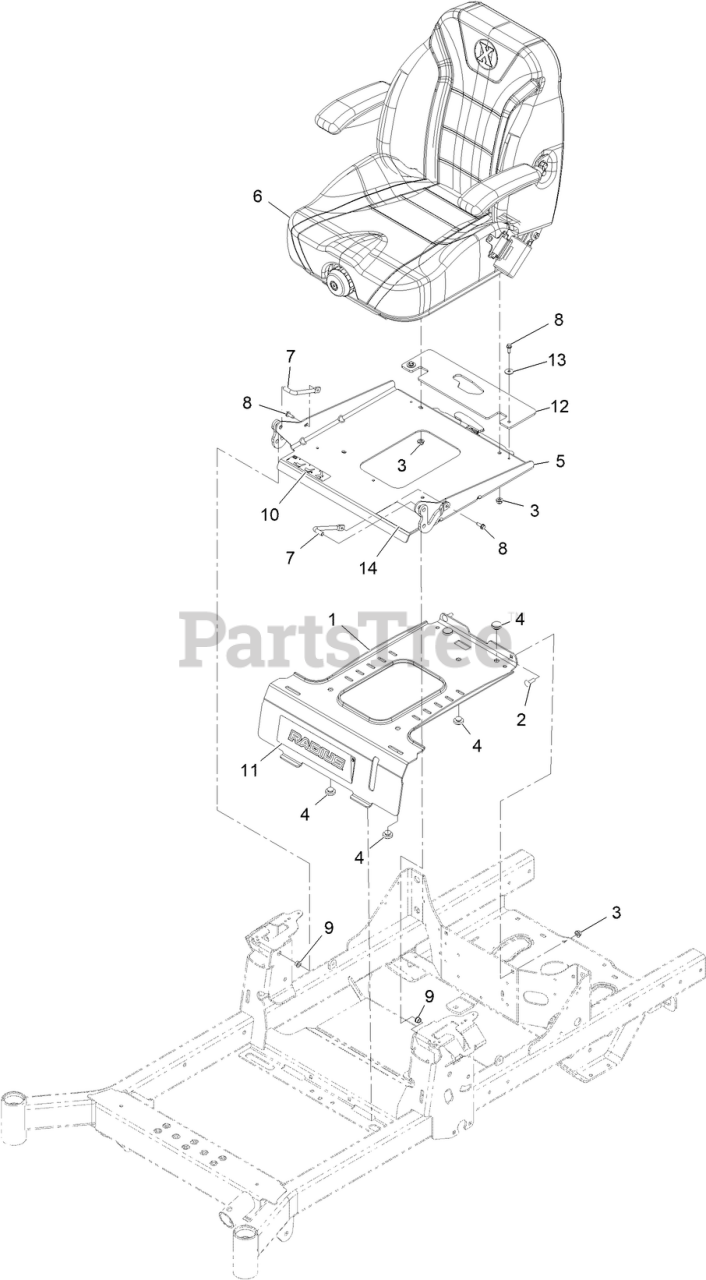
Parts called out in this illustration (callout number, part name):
1	PLATE-RETAINER, TANK
2	SCREW-CARR
3	NUT-HF, NI
4	BUMPER-SEAT
5	SEAT PAN AND LATCH ASM
6	Seat, Susp.
7	PIN-PIVOT, SEAT
8	SCREW-HWH, THREAD ROLL
9	BUSHING-FLANGED
10	DECAL-LATCH, SEAT
11	DECAL-RADIUS LOGO
12	GUARD-SEAT, RUBBER
14	DECAL-SERVICE AID
